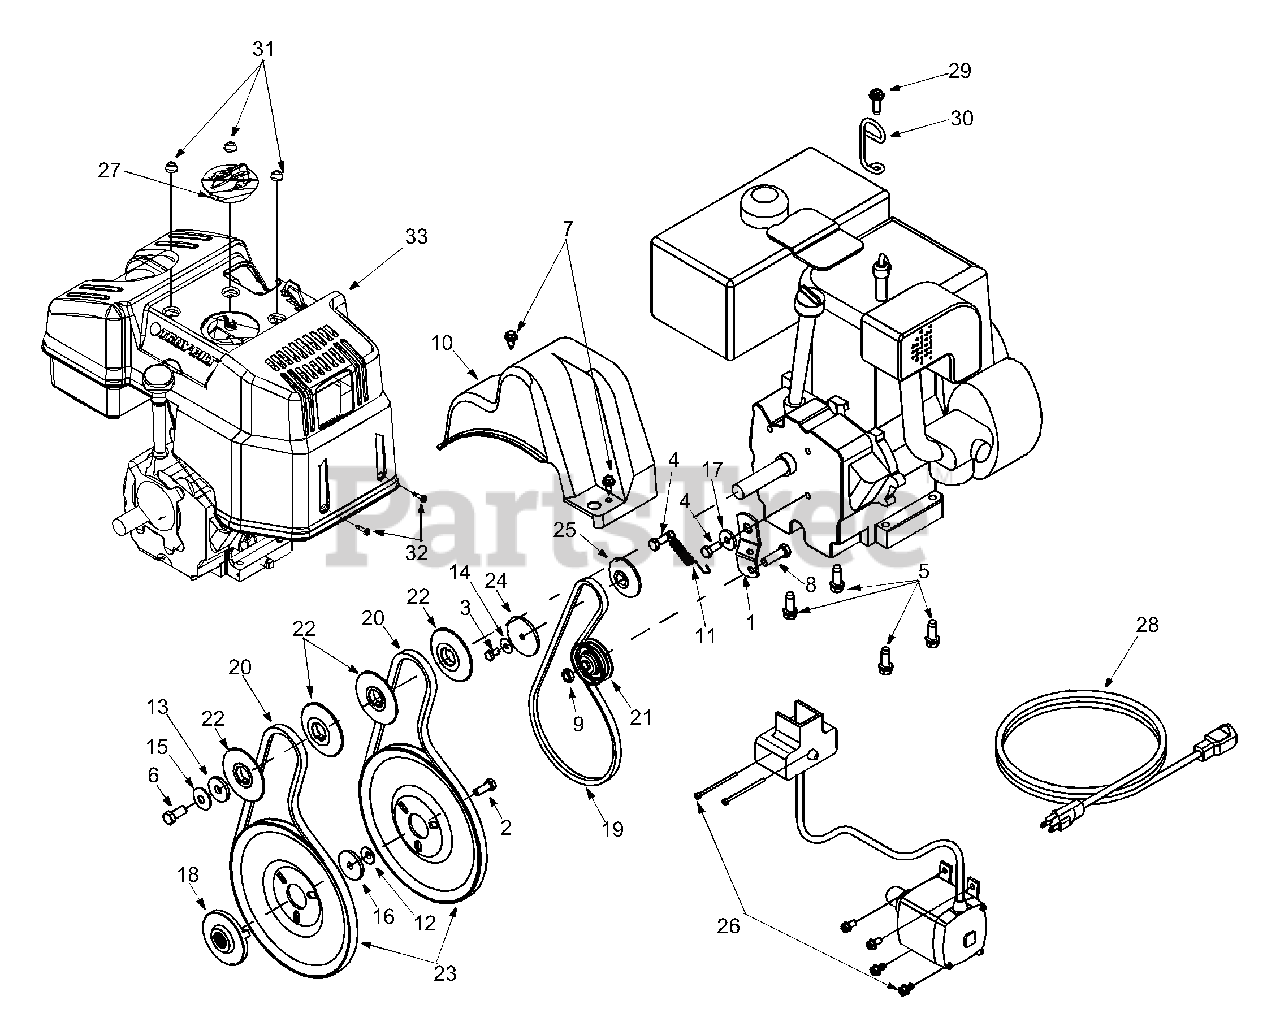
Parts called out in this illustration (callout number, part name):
3	Hex Hd. Cap Screw 1/4-28 Thd.
4	Hex Hd. Cap Screw 5/16-24 Thd.
5	TT-Tap Screw 3/8-16 Thd.
6	Hex Hd. Screw 3/8-24
7	TT-Tap Screw 1/4-20 Thd.
8	Hex Hd. Cap Screw 3/8-16 Thd.
10	Belt Cover
11	Extension Spring
12	Bell Washer
13	Fl-Washer .406 I.D. x 1.25 O.D.
14	Bell Washer
15	Bell Washer
16	Fl-Washer .34 I.D. x .50 O.D.
17	Shoulder Spacer
18	Pulley Adapter
19	V-Belt 3/8
20	Belt
21	Flat Idler Pulley
22	Half Pulley
23	Auger Pulley
24	Half Pulley
25	Half Pulley
26	Electric Start Kit
27	Spark Plug Cap
28	Extension Cord
29	Part of Engine
30	Cable Control Wire
31	Flange Lock Nut, 5/16-18 Thd.
32	Screw, #10-16 x .75
33	Engine Shroud
